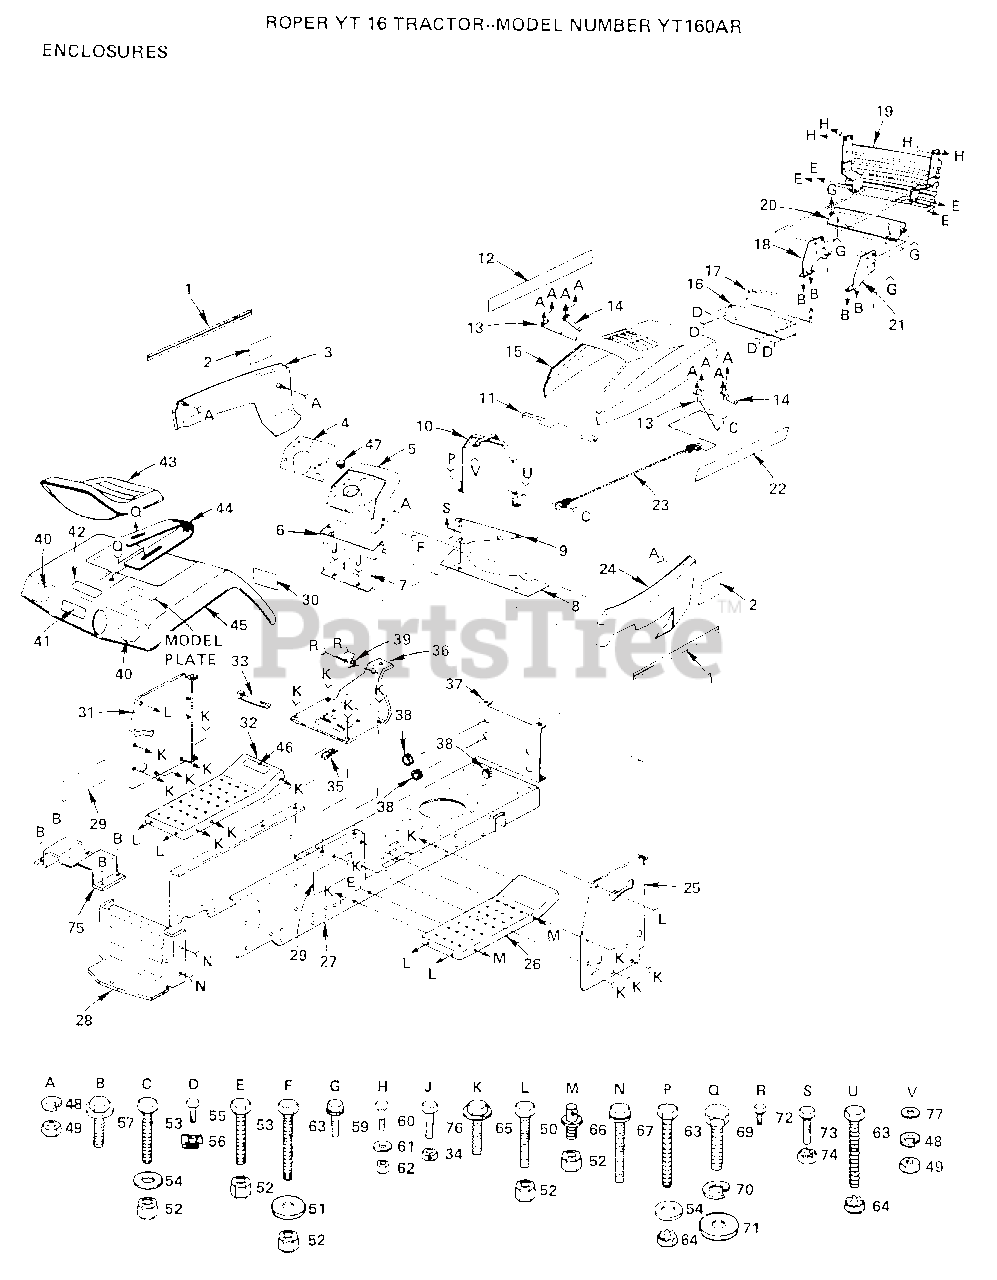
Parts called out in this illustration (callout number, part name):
6	LOWER DASH
7	DECAL, INSTRUCTION
9	PLATE, SUPPORT BATTERY
11	FOAM-STRIP LT
18	SUPPORT-GRILL LT
30	DECAL-CAUTION
33	WIRE TIE
35	CLIP T
38	SNAP BUSHING T
41	DECAL-CAUTION
47	PLUG-DASH T
51	WASHER
53	BOLT
54	WASHER
56	"""J"" FASTENER LT"
57	SCREW
59	SCREW
60	BOLT T
64	NUT
65	SCREW LT
66	PIN SUSPENS. LTV
67	SCREW GTV
69	BOLT
71	WASHER
73	BOLT
75	BRACKET ASSY - FENDER
77	WASHER PM
